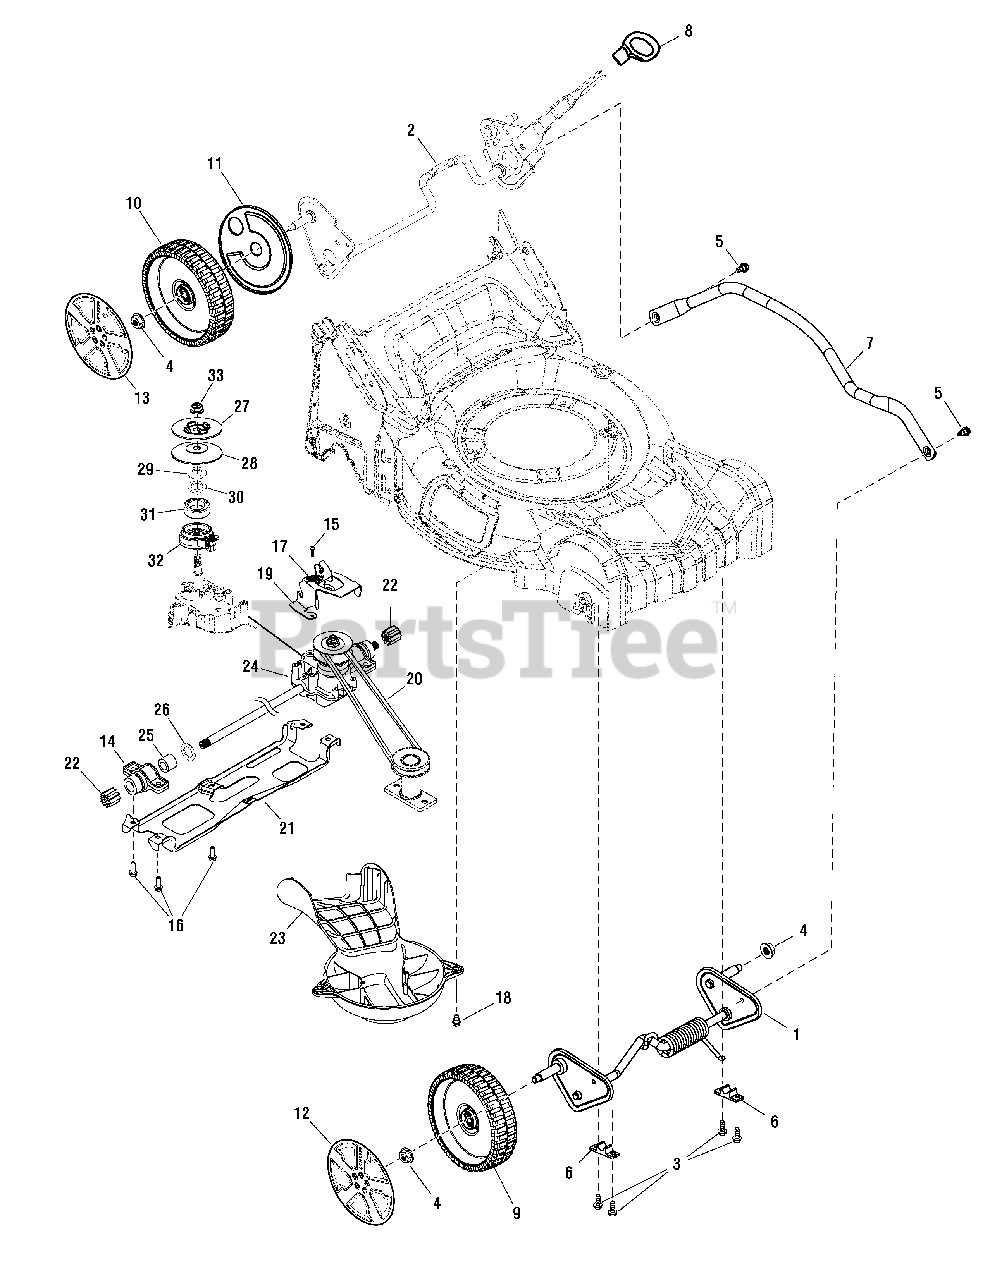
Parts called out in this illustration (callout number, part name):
1	AXLE, Front
2	AXLE, Rear
3	SCREW, 1/4-15X3/4, Self-Tapping, BZ
4	NUT, Hex Flange, Nylock, 3/8-16
5	SCREW, 1/4-20 x 1/2
6	BUSHING, Lock
8	KNOB, Red
8	KNOB, Black
9	WHEEL, 200 x 49
10	WHEEL, Drive
11	DUST COVER, Wheel
12	HUBCAP, Front
13	HUBCAP, Rear
14	BEARING ASSEMBLY
15	SCREW, Hex Washer Head, .159 x .43
16	SCREW, 1/4-15 x 1-1/4
18	SCREW, 1/4-20 x 1/2
19	BRACKET
21	SUPPORT
22	GEAR, 9 Tooth
23	COVER, Rear
24	TRANSMISSION
27	PULLEY HALF, Upper
28	PULLEY HALF, Lower
29	SHIM, 20
30	SHIM, 10
31	BEARING
32	CAM PULLEY, Speed
33	NUT, Lock
